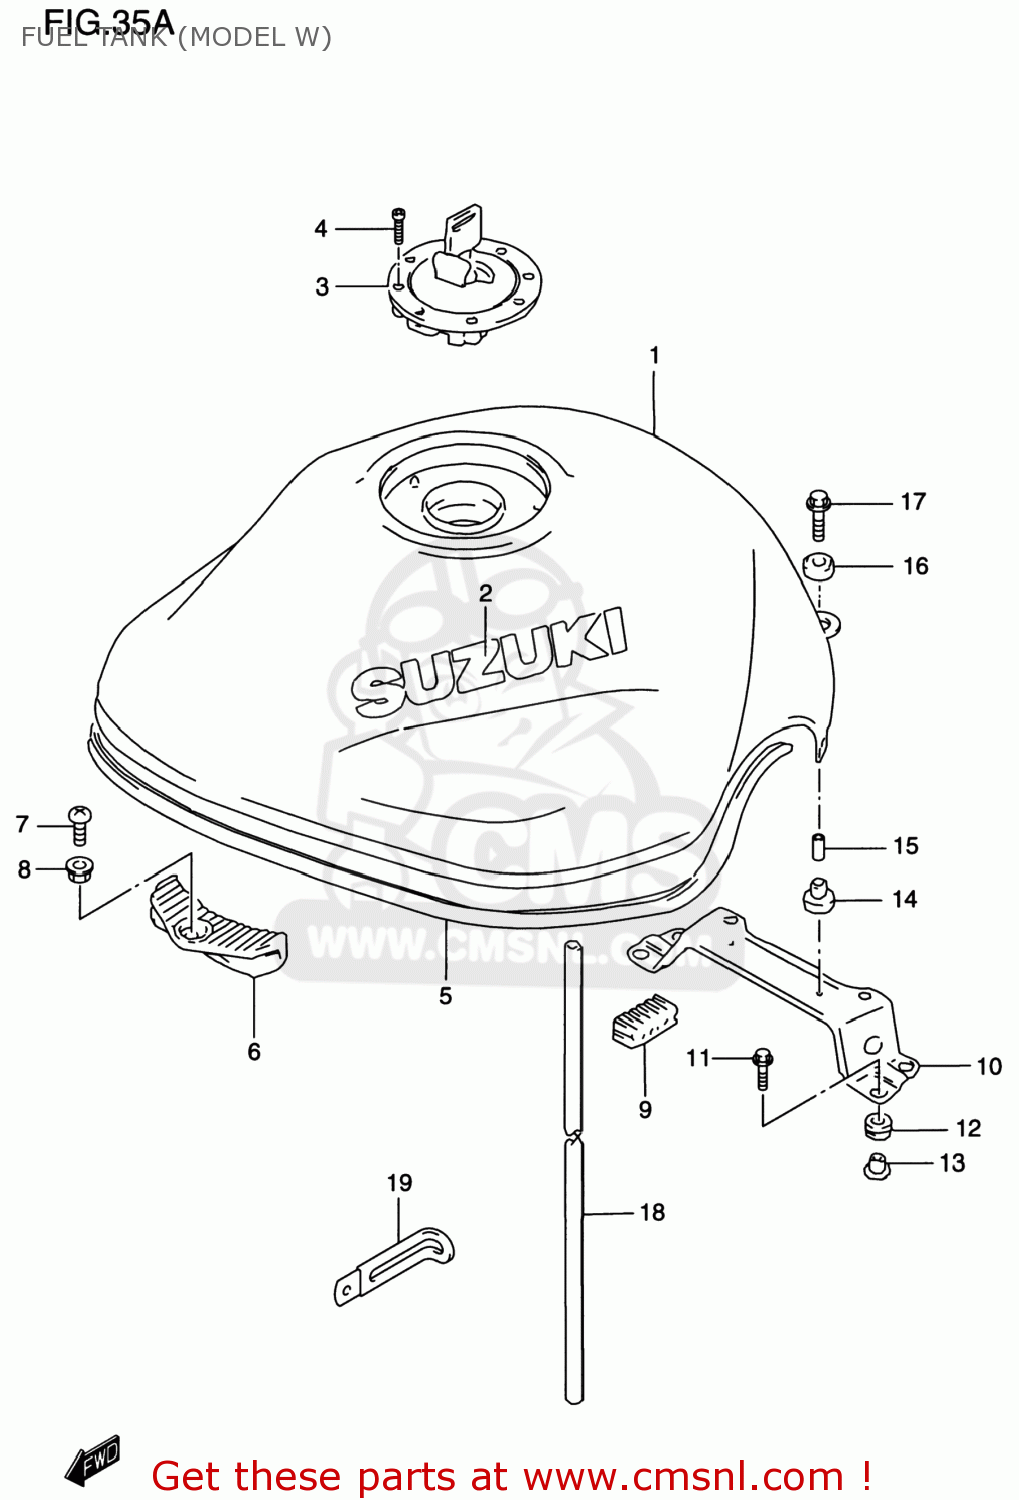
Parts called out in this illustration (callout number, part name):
1	TANK ASSEMBLY,FUEL
2	EMBLEM,FUEL TANK
3	CAP SET,FUEL
4	BOLT(5X20)
5	MOLDING
6	CUSHION,FUEL TANK FR
7	SCREW
8	WASHER
9	CUSHION,SEAT(40X20X15)
10	BRACKET,FUEL TANK RR
11	BOLT(6X25)
12	CUSHION
13	WASHER
14	CUSHION
15	SPACER(6.5X9X18)
16	CUSHION
17	BOLT(6X30)
18	HOSE(7X10.2X2000)
19	CLAMP(L:97)
